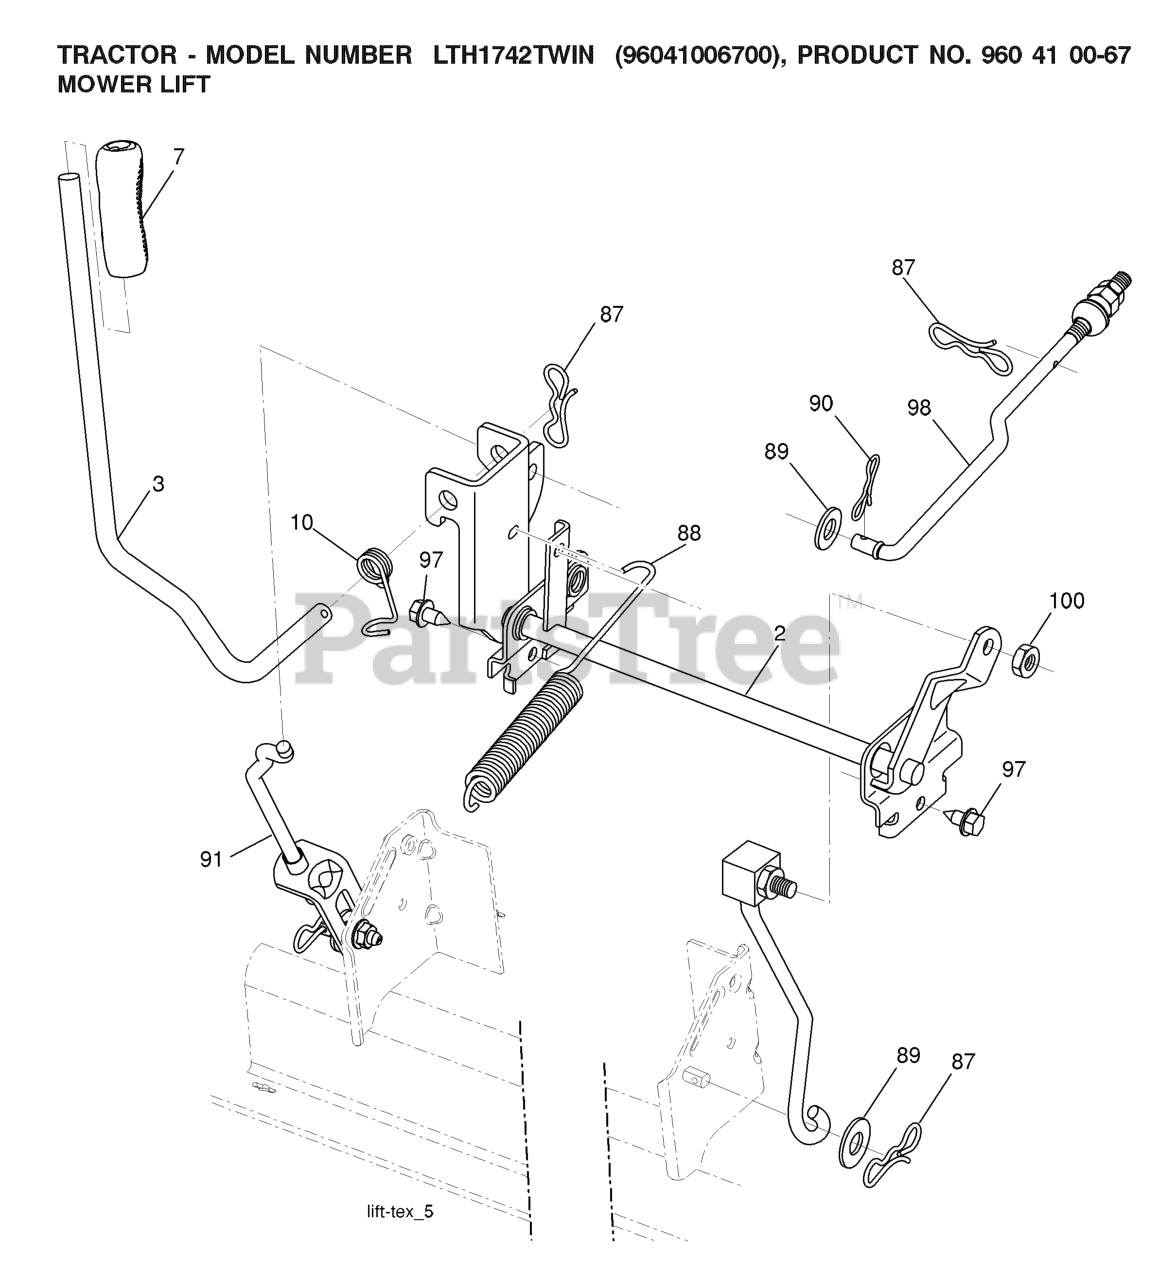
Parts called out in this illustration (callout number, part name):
2	SHAFT.ASM.LIFT.CROSS.H
3	LEVER.LIFT.HANDLE.LT
7	GRIP.HANDLE.LIFT.PVC.BLACK
10	SPRING.TORSION.LIFT.HANDLE
87	PIN.COTTER.7/16.BOW TI.
88	SPRING.LIFT.ASSIST
89	WASHER.CLEAR.ZINC
90	PIN.COTTER.5/16.BOW TI
91	LINK.ASM.LIFT.REAR
97	SCREW, 3/8-16X3/4
98	LINK.ASM.SUSP.FRONT.MW
100	LOCKNUT
